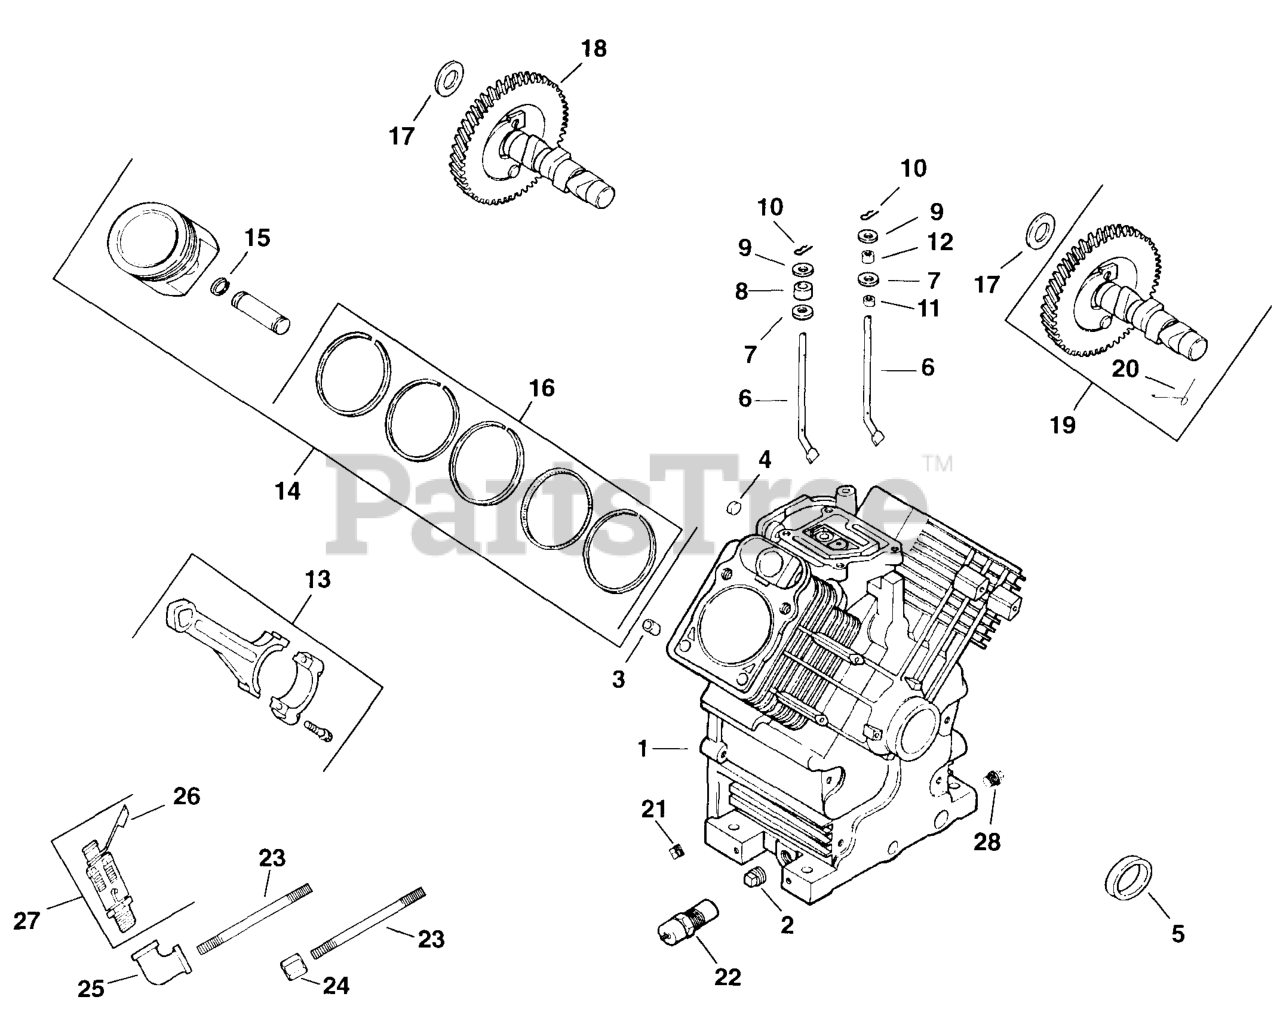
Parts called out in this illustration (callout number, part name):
2	Plug, Sq. Hd. Solid 3/8" N.P.T.F.
3	Pin, Dowel Locating
4	Plug, Cup
5	Seal, Oil Front
6	Shaft, Governor Cross
7	Washer, Plain 1/4"
8	Seal, Governor Cross Shaft
9	Washer, Plain 1/4"
10	Pin, Hitch
13	Connecting Rod (Std.)
13	Connecting Rod (.25)
14	Piston W/Ring Set (Std.)
14	Piston W/Ring Set (.25)
14	Piston W/Ring Set (.50)
15	Retainer, Piston Pin
16	Ring Set (Std.)
16	Ring Set (.25)
16	Ring Set (.50)
17	Shim, Camshaft (A.R.) (White) (.02725 - .02875)
17	Shim, Camshaft (A.R.) (Blue) (.02925 - .03075)
17	Shim, Camshaft (A.R.) (Red) (.03125 - .03275)
17	Shim, Camshaft (Yellow) (.03325 - .03475)
17	Shim, Camshaft (A.R.) (Green) (.03525 - .03675)
17	Shim, Camshaft (A.R.) (Gray) (.03725 - .03875)
17	Shim, Camshaft (A.R.) (Black) (.03925 - .04075)
18	Camshaft
